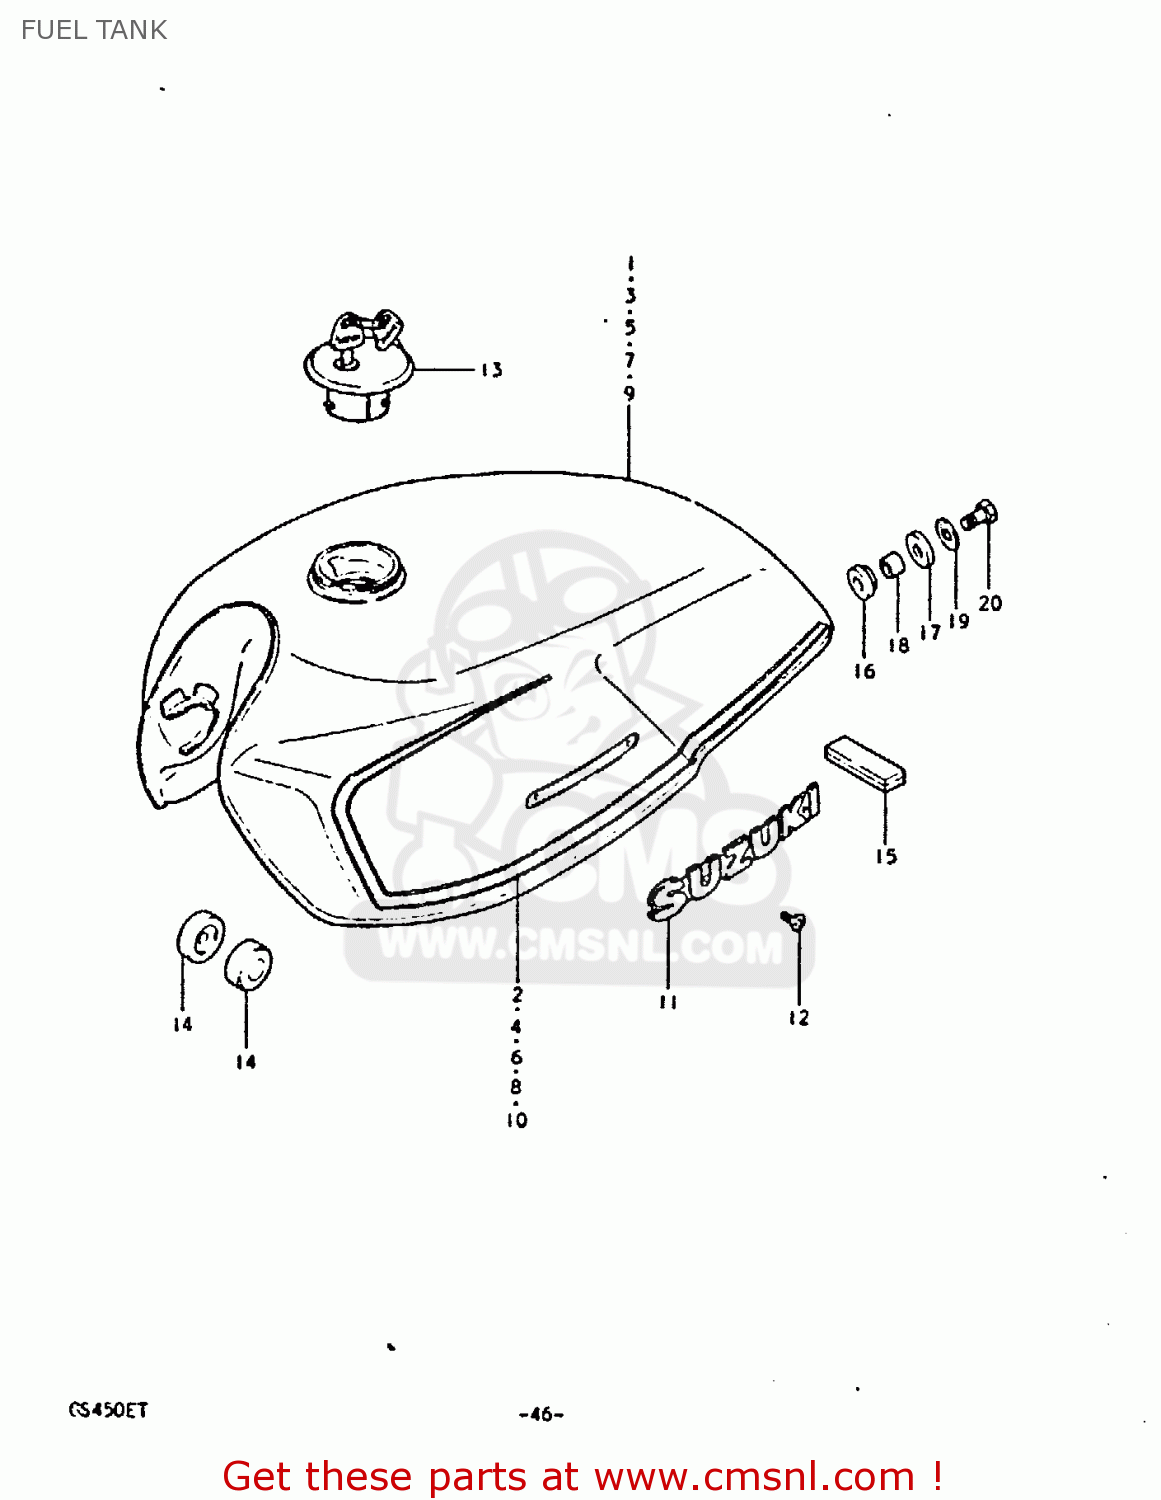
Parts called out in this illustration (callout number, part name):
1	TANK, FUEL
2	TAPE SET
3	TANK, FUEL
4	TAPE SET
5	TANK, FUEL
6	TAPE SET
7	TANK, FUEL
8	TAPE SET
11	EMBLEM
12	SCREW 3X6
13	CAP SET,FUEL TANK
14	CUSHION
15	CUSHION
16	CUSHION
17	CUSHION
18	SPACER(8.5X12X19)
19	WASHER (8.5X29X1.6)
20	BOLT (8X30)
